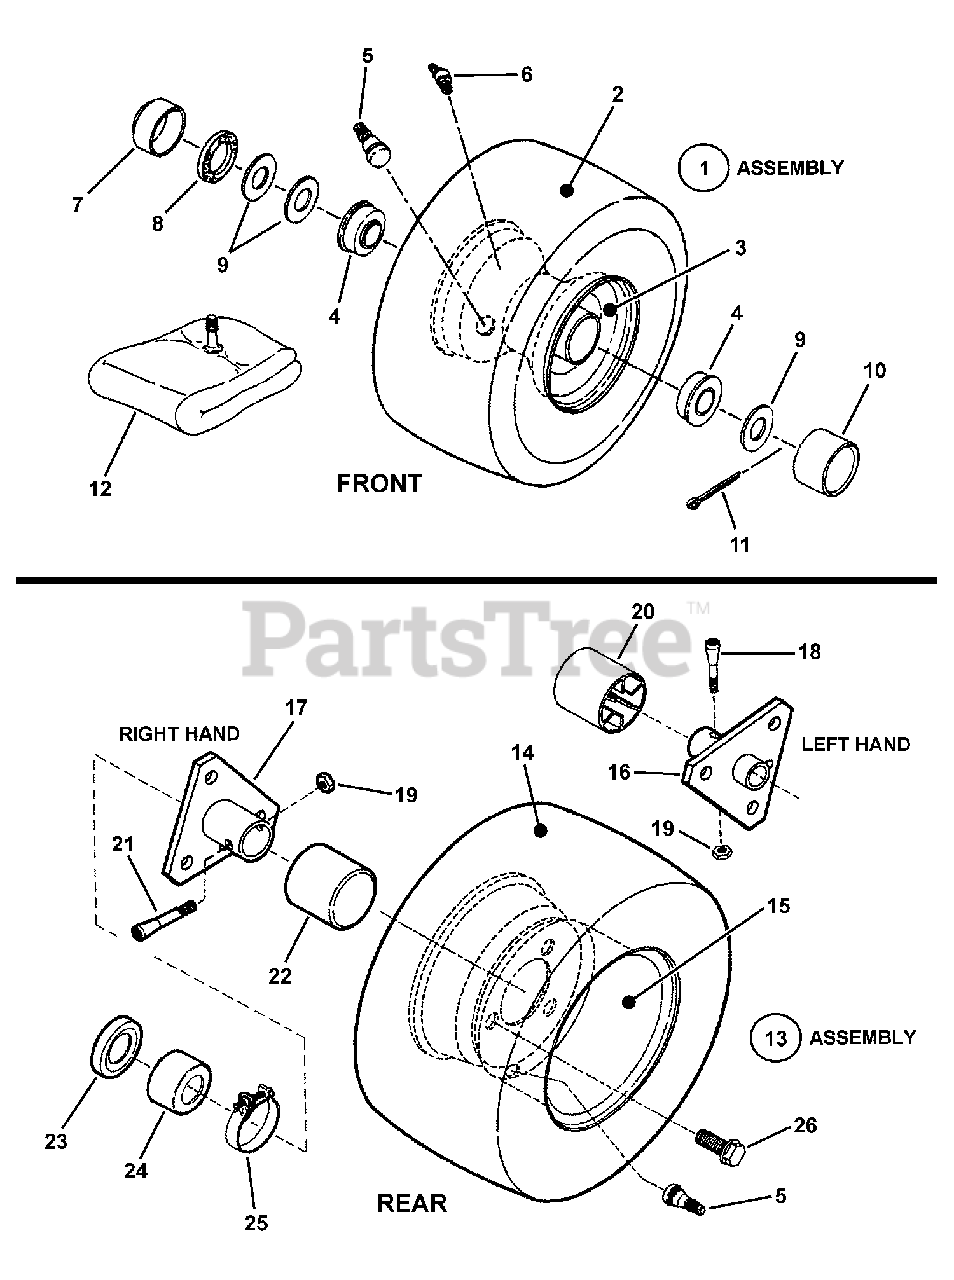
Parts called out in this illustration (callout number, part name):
1	ASSEMBLY, Front Tire & Rim (Complete)
2	TIRE, 11 x 4.00-4 (Kenda)
3	RIM (For 4.10/3.50 x 4 Tire)
4	BALL BEARING, Flange (3/4" I.D.)
5	VALVE STEM, Snap In
6	* LUBE Fitting, Straight (for 3/16" hole)
6	* LUBE Fitting, Straight (for 1/4" hole)
6	* LUBE Fitting, 90 Degree, Ball Check (for 1/4" hole)
6	* LUBE Fitting, 90 Degree, Ball Check (for 5/16" hole)
7	CAP, Dust
8	FELT SEAL
9	WASHER, .77 x 1.13 x .06 Flat
10	HUB CAP
11	COTTER PIN, 5/32 x 1"
12	TUBE, Inner (For 4.10/3.50 x 4 Tire)
13	ASSEMBLY, Rear Tire & Rim (28" & 33" Models)
14	TIRE, 16-6.50 x 8
15	RIM, Extra Wide (For 16/7.50 x 8 Tire) (33" Models)
16	HUB, Rear Wheel LH, 3 Hole 3/4" ID
17	HUB, Rear Wheel RH, 3 Hole 1" ID
18	AXLE BOLT, Left Hand (5/16-24 x 1-5/8" Tapered)
19	NUT, Wheel Bolt, 5/16-24 Hex Center Lock
20	CAP, Hub, L. H. (Long Axle)
21	WHEEL BOLT, Right Hand (5/16-24 x 2" Tapered)
22	CAP, Hub
23	SEAL, 1.22" ID x 1.875" OD
24	CAP, Seal 1.0" ID x 1.67" OD, Right Hand
25	CLAMP, Right Hand 2"
25	CLAMP, Right Hand 2.69"
26	BOLT, 1/2-20 x 3/4" Lug, GR 5
